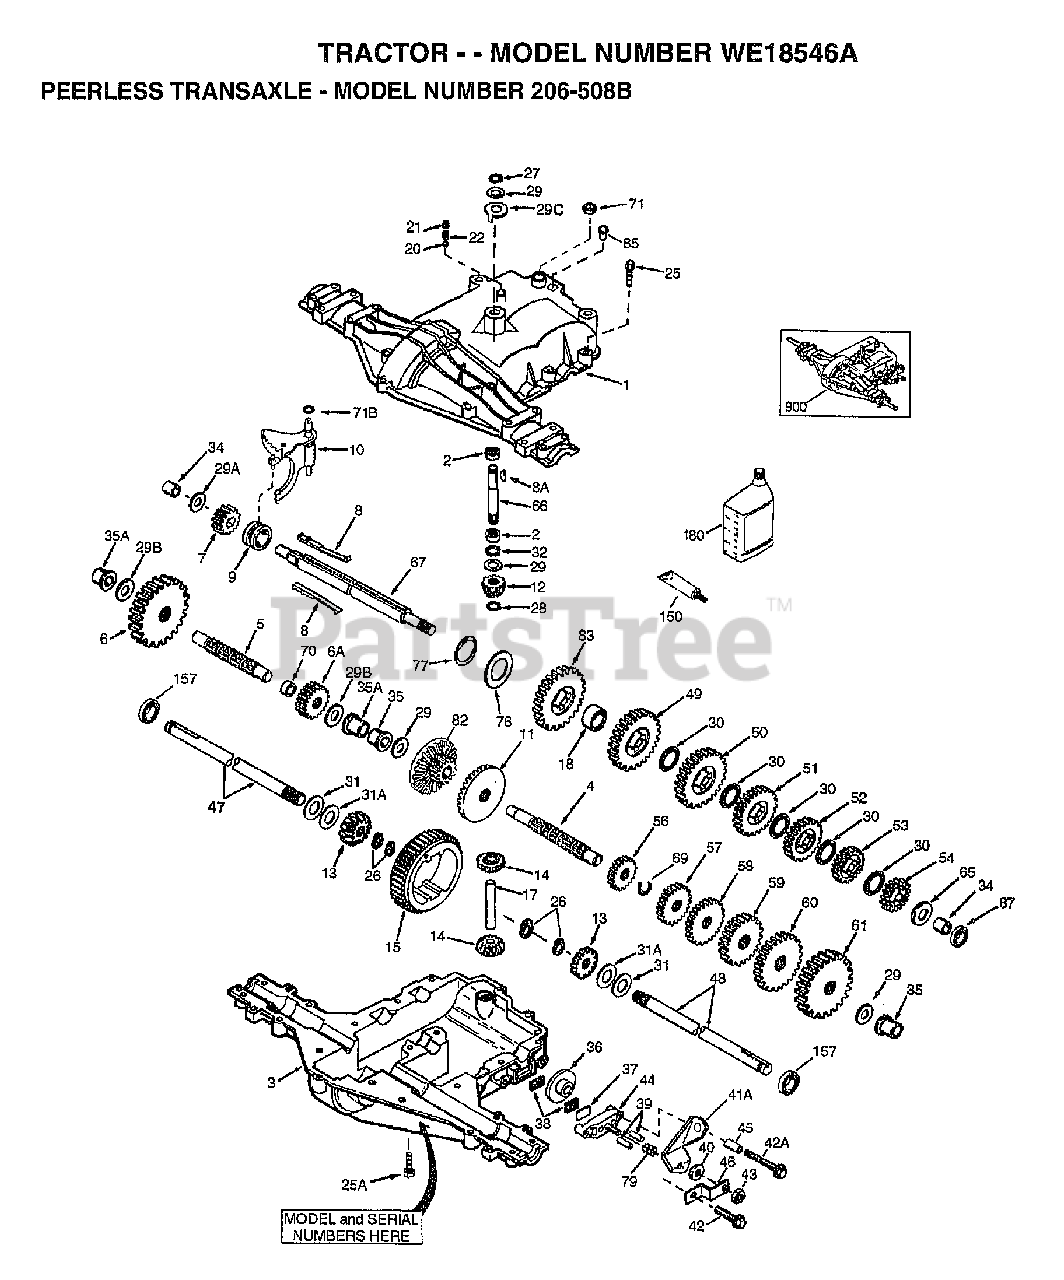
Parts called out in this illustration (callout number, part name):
1	TRANSAXLE COVER
2	NEEDLE BEARING 5/8" ID
3	TRANSAXLE CASE
4	COUNTERSHAFT
5	OUTPUT SHAFT
6	SPUR GEAR (38 TEETH)
6A	SPUR GEAR (15 TEETH)
7	SPUR GEAR (11 TEETH)
8A	KEY, WOODRUFF
9	COLLAR, SHIFTER
10	SHIFT ROD & FORK
11	BEVEL GEAR (30 TEETH)
12	INPUT BEVEL PINION (13TEETH)
13	BEVEL GEAR (13 TEETH)
14	BEVEL PINION (13 TEETH)
15	RING GEAR (43 TEETH)
18	SPACER, NEUTRAL
20	BALL STEEL, 5/16" DIA.
21	SCREW, 3/8-16 X 3/8"
25A	SCREW 1/4-20 X 1-3/8"
26	RING RETAINER
27	RING, RETAINER
28	RETAINING RING
29	WASHER THRUST
29B	WASHER THRUST
29C	P/N CONFLICT - CHECK WITH SUPPLIER
30	WASHER THRUST
31A	FLAT WASHER
32	OIL SEAL 5/8"
34	BUSHING 9/16"
35	FLANGED BUSHING 5/8" ID
35A	FLANGED BUSHING 3/4"
37	PLATE BRAKE PAD
41A	BRAKE LEVER
42A	SCREW, 1/4-20 X 2-1/4
43	LOCKNUT 5/16-24
44	HOLDER BRAKE PAD
46	BRKT BRAKE LEVER
49	SPUR GEAR (29 TEETH)
50	SPUR GEAR (27 TEETH)
51	SPUR GEAR (23 TEETH)
52	SPUR GEAR (19 TEETH)
53	SPUR GEAR (16 TEETH)
54	SPUR GEAR (15 TEETH)
56	SPUR GEAR (11 TEETH)
57	SPUR GEAR (13 TEETH)
58	SPUR GEAR (17 TEETH)
59	SPUR GEAR (21 TEETH)
60	SPUR GEAR (24 TEETH)
61	SPUR GEAR (25 TEETH)
66	INPUT SHAFT
67	SHIFTER & BRAKE SHAFT
69	RETAINING RING
70	SPACER .890
71	SEAL SQUARE CUT
76	WASHER, THRUST
77	INVERTED RETAINING RING
82	BEVEL & SPUR GEAR (30 & 13 TEETH)
83	SPUR GEAR (27 TEETH)
85	OIL FILL PLUG
87	OIL SEAL 9/16"
150	LIQUID GASKET RTV SILICONE
157	OIL SEAL 3/4"
180	GEAR OIL 80W90
